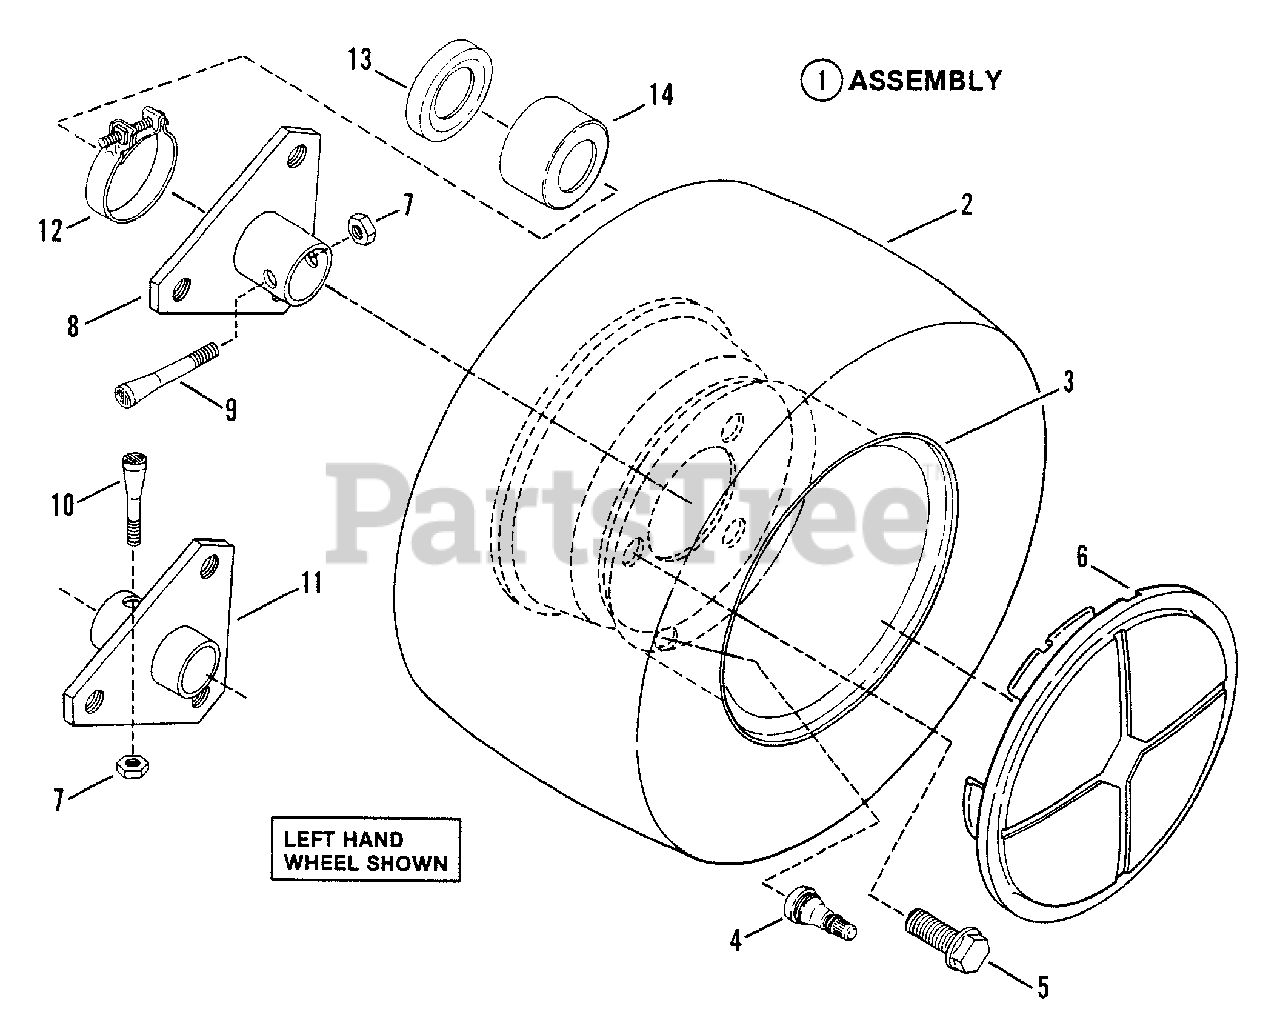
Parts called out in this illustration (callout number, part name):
1	ASSEMBLY, Rear Tire & Rim (33" Deck) (LT120D33)
2	TIRE, 18-7.50 x 8
3	RIM, 8 x 5-3/8
4	VALVE, Air (Snap-in)
5	BOLT, 1/2-20 x 3/4" Lug
6	WHEEL COVER
7	NUT, 5/16-24 Hex Lock
8	HUB, Rear Wheel (Left Hand) 1.126" ID
9	BOLT, 5/16-24 x 2" Tapered (Left Hand)
10	BOLT, 5/16-24 x 1 5/8" Tapered (Right Hand)
11	HUB, Rear Wheel (Right Hand) .75" ID
12	CLAMP
13	SEAL, Oil (Left Hand)
14	CAP, Seal (Left Hand)
